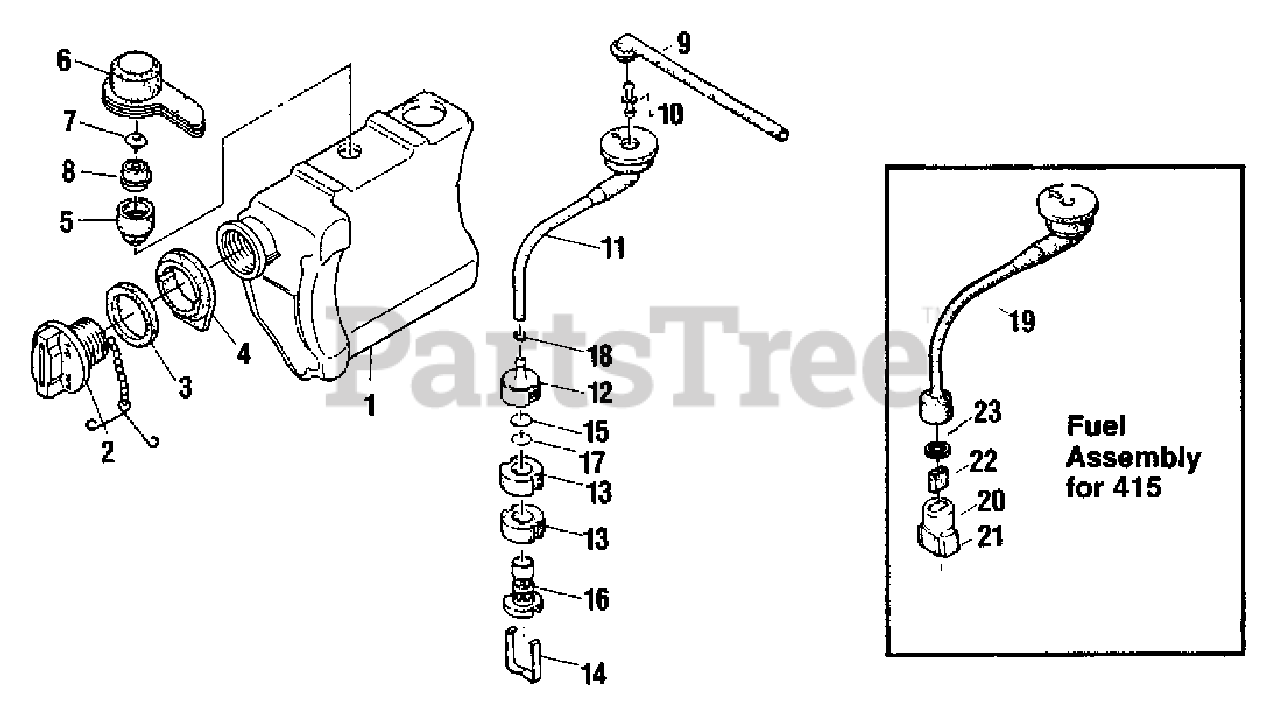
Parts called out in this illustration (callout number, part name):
1	TANK, FUEL
2	CAP, FUEL
3	GASKET, CAP
4	SUPPORT, FUEL TANK
5	HOLDER, VALVE
6	CAP, BREATHER
7	VALVE, BREATHER
8	RETAINER, BREATHER
9	PIPE - FUEL
10	CONNECTOR, PIPE
11	PIPE - FUEL
12	WEIGHT, FUEL FILTER
13	ELEMENT, FUEL FILTER
14	CLIP, FILTER
16	CASE, FILTER
17	RING, RETAINING
18	RING, RETAINING - 6
19	PIPE - FUEL
20	WEIGHT, FUEL FILTER
21	FILTER, FUEL - A
22	FILTER, FUEL - B
23	CLIP
